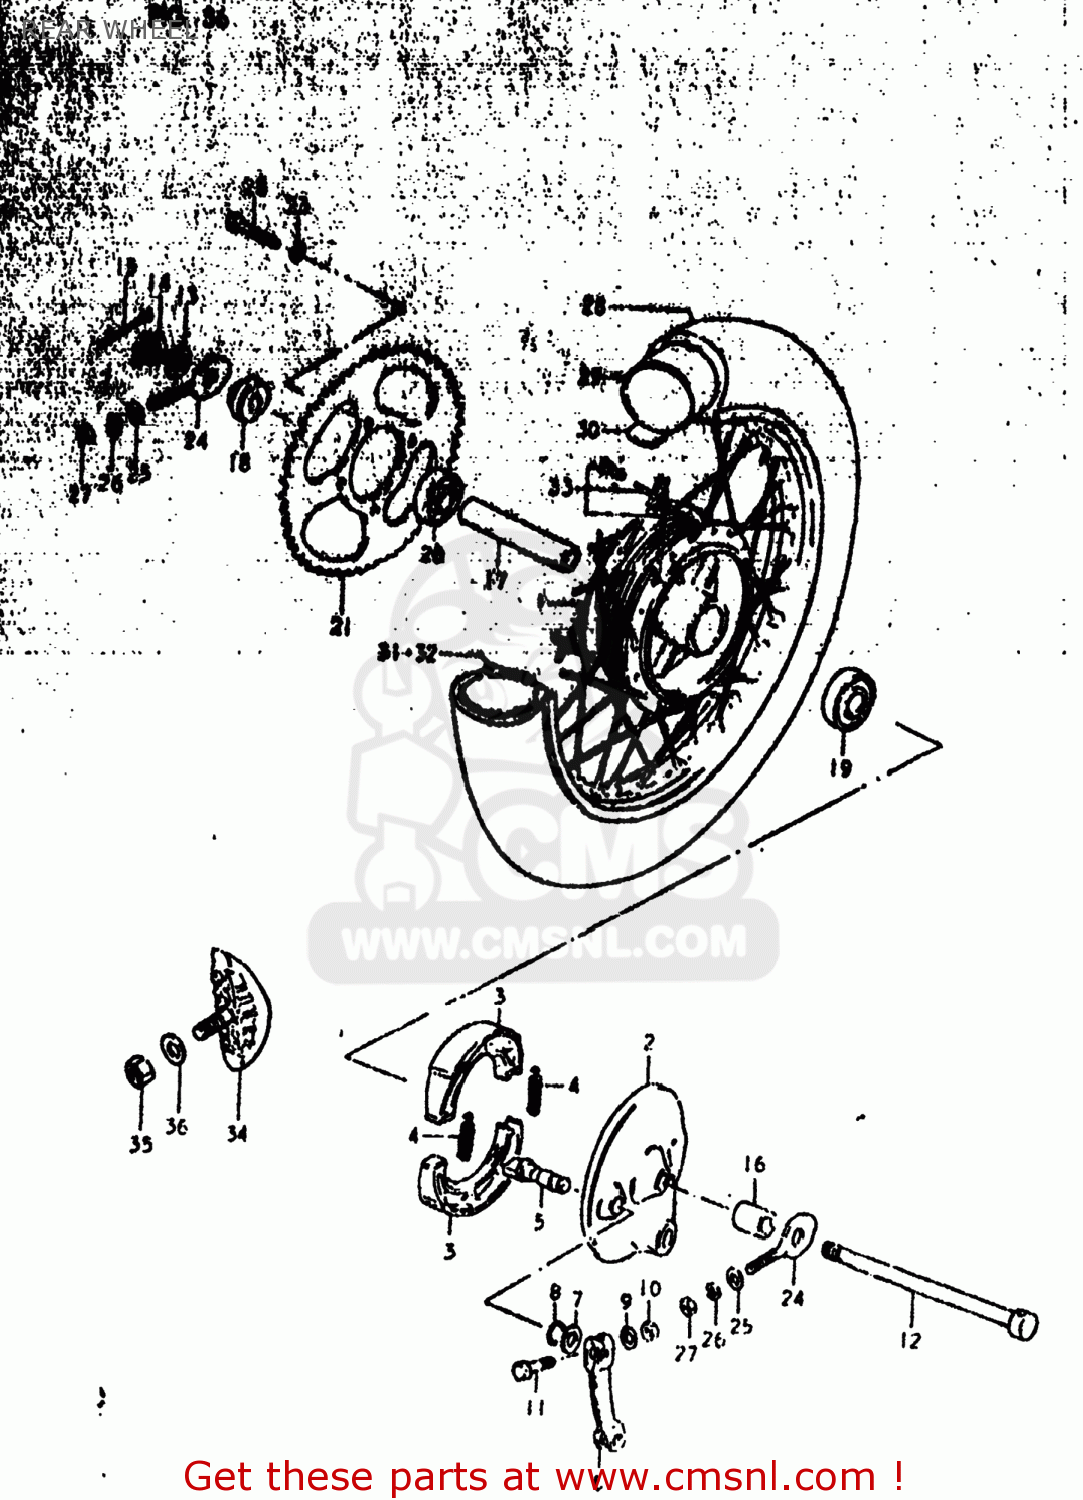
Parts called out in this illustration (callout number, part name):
1	DRUM SET,REAR HUB
2	PANEL,REAR BRAKE ANCHOR
3	SHOE,BRAKE
4	SPRING(L:34)
5	CAM,FRONT BRAKE
6	LEVER,REAR BRAKE CAM
7	WASHER (14.5X22X1.6)
8	O-RING (D:2.4 ID:13.8)
9	WASHER
10	NUT
11	BOLT(6X33)
12	AXLE,REAR
13	WASHER
14	NUT 12MM
15	COTTER PIN
16	SPACER (12.1X22X27)
17	SPACER(12.6X19X91)
18	SPACER,RR AXLE,L
19	BEARING
20	BEARING
21	SPROCKET,RR(NT:42)
22	BOLT
23	LOCK WASHER
24	ADJUSTER,CHAIN,R
25	WASHER
26	LOCK WASHER
27	NUT
28	TIRE
29	TUBE,INNER
30	PROTECTOR,INNER TUBE
31	RIM,RR WHEEL(1.60X12)
32	RIM,REAR WHEEL
33	SPOKE SET,REAR
34	STOPPER,BEAD
35	NUT
36	WASHER
